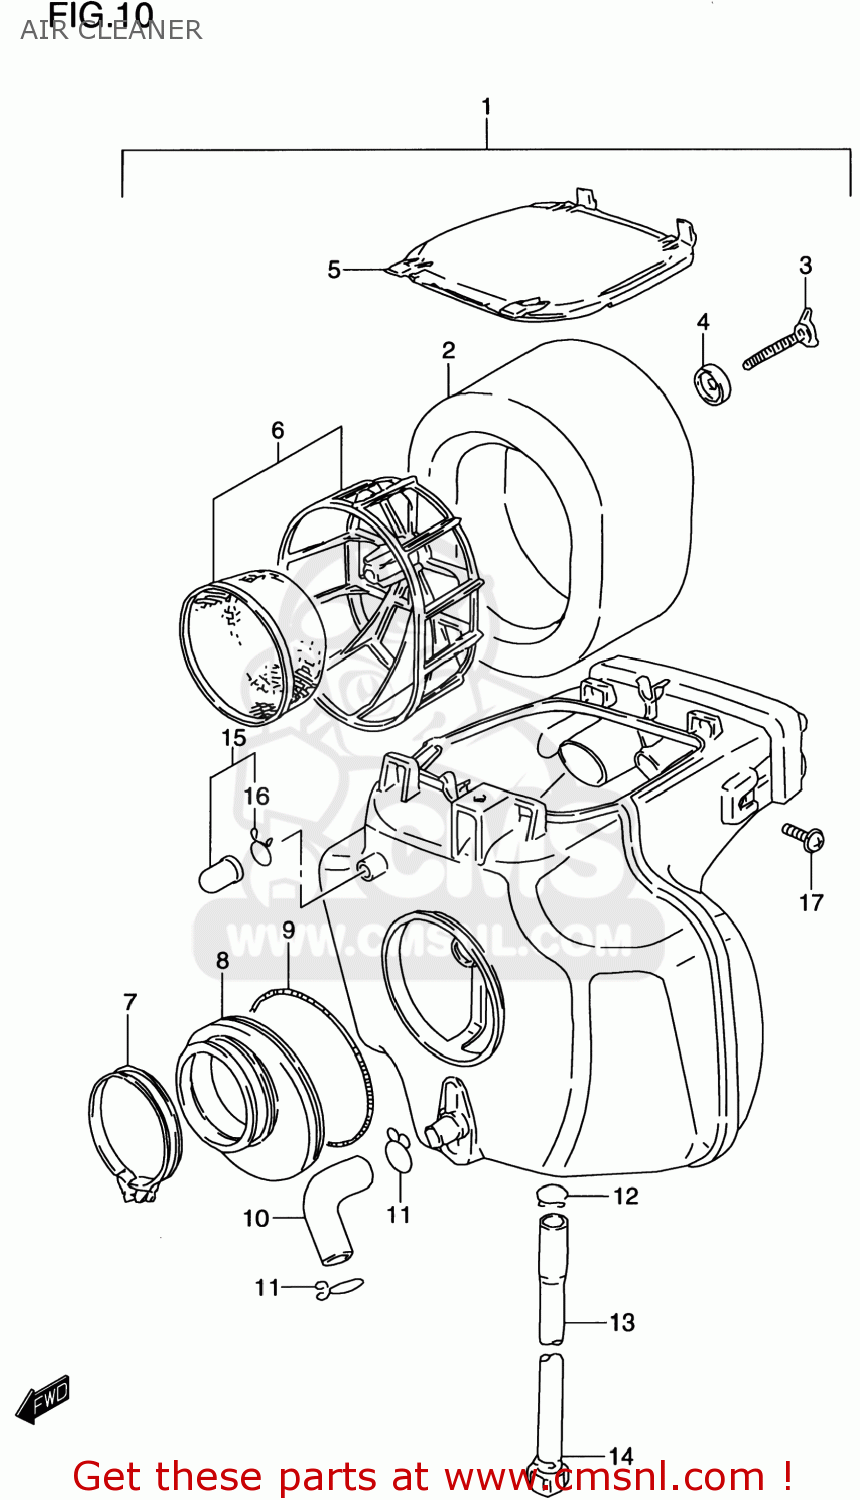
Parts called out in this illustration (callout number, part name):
1	CLEANER ASSY,AIR
2	FILTER
3	BOLT,WING
4	WASHER,FILTER HOLDER
5	CAP
6	HOLDER
7	CLAMP
8	TUBE,AIR CLEANER OUTLET
9	CLAMP,AIR CLEANER SIDE
10	TUBE,BREATHER
11	CLIP
12	CLIP
13	TUBE,DRAIN
14	CLIP
15	PLUG,DRAIN
16	CLIP
17	SCREW
